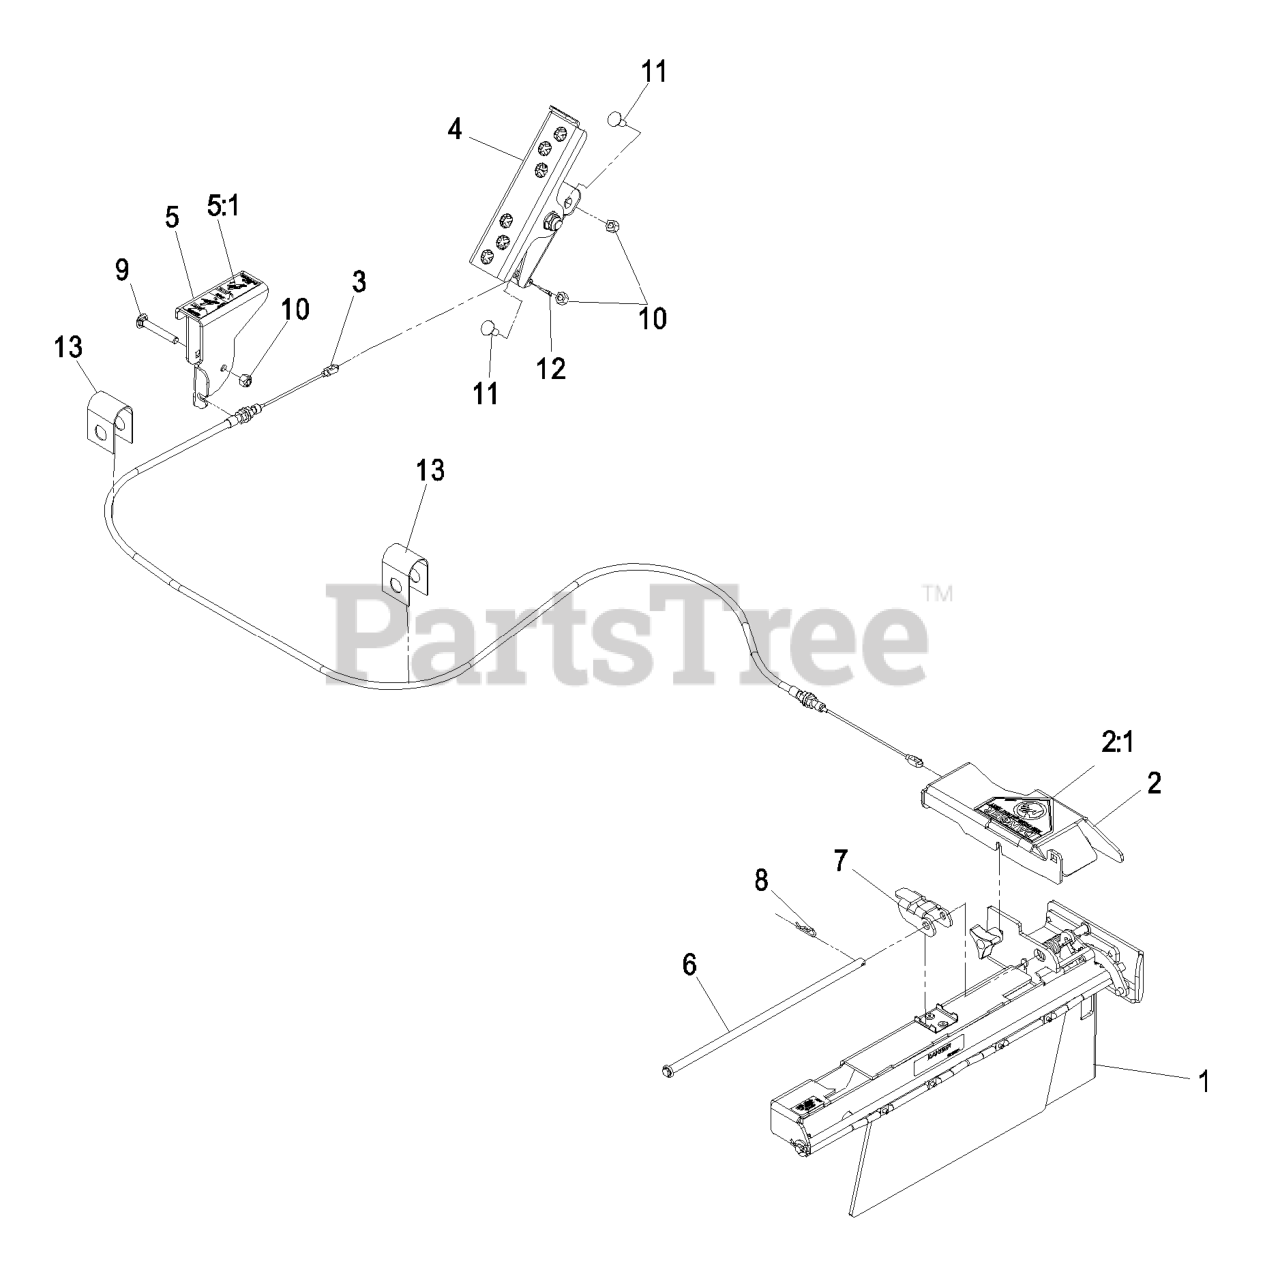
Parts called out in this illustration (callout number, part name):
1	Asm, Gate Linkage
2	Asm, Cable Bracket
2:1	Decal, Danger
3	Cable, Discharge Gate
4	Asm, Gate Pedal
5	Asm, Cable Bracket
5:1	Decal, Operation
6	Rod, Chute Pivot
7	Bracket, Link Pivot
8	Hairpin, Cotter
9	Bolt, Carriage 5/16-18 X 2 1/4
10	Nut, Nyloc 5/16-18
11	Bolt, Carriage 5/16-18 X 3/4, Short Neck
12	Pin, Cotter 3/32 X 1/2
13	Support, Cable
